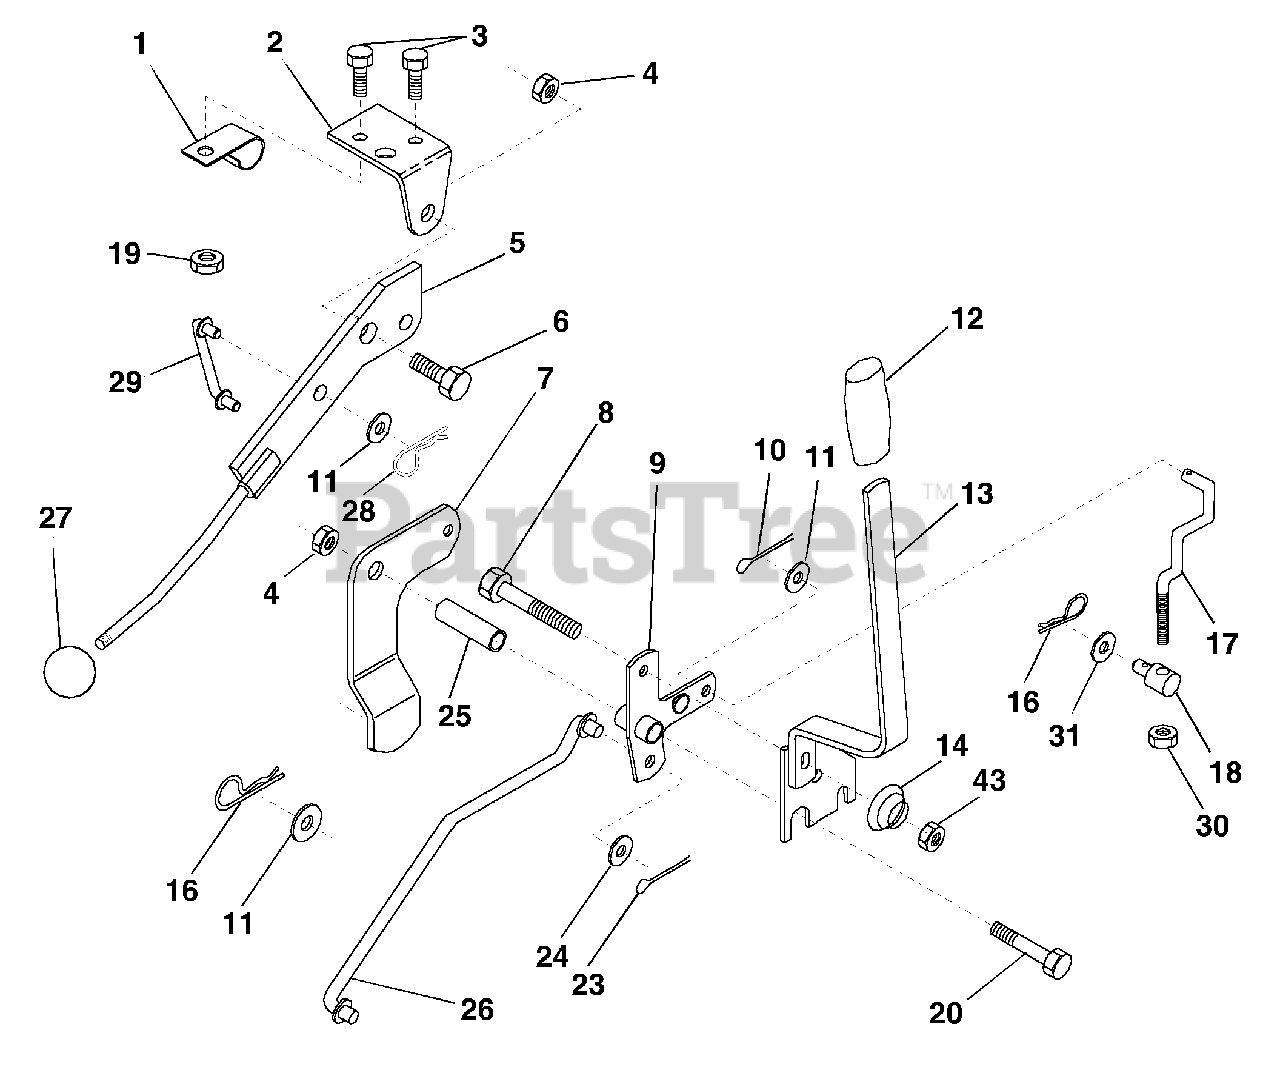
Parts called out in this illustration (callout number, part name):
1	Clip, Insulated
2	Bracket, Mower Clutch
3	Bolt, Fin. Hex 1/4-20 UNC x 1/2 Gr. 5
4	Nut, Crownlock 3/8-16 UNC
5	Assembly, Clutch Lever
6	Bolt, Shoulder
7	Assembly, Mower Clutch Arm
8	Bolt, Hex 3/8-16 UNC x 2-1/4
9	Assembly, Bellcrank Lift
10	Pin, Cotter 1/8 x 3/4
11	Washer 13/32 x 13/16 x 16 Ga.
12	Grip, Handle
13	Assembly, Lift Handle
14	Spring, Compression
16	Retainer, Spring
17	Link, Front Lift
18	Trunnion, Threaded 3/8-16
19	Nut, Crownlock 1/4-20
20	Bolt, Fin. Hex 3/8-16 UNC x 2-3/4
23	Pin, Cotter 1/8 x 1
24	Washer 17/32 x 1 x 12 Ga.
25	Tube, Spacer
26	Rod, Mower Lift
28	Retainer Spring
29	Link, Mower Clutch
30	Nut Hex Jam 3/8-16 x 1.30
31	Washer 13/32 x 1-1/4 x 12 Ga.
43	Nut Lock Flg 3/8-16
